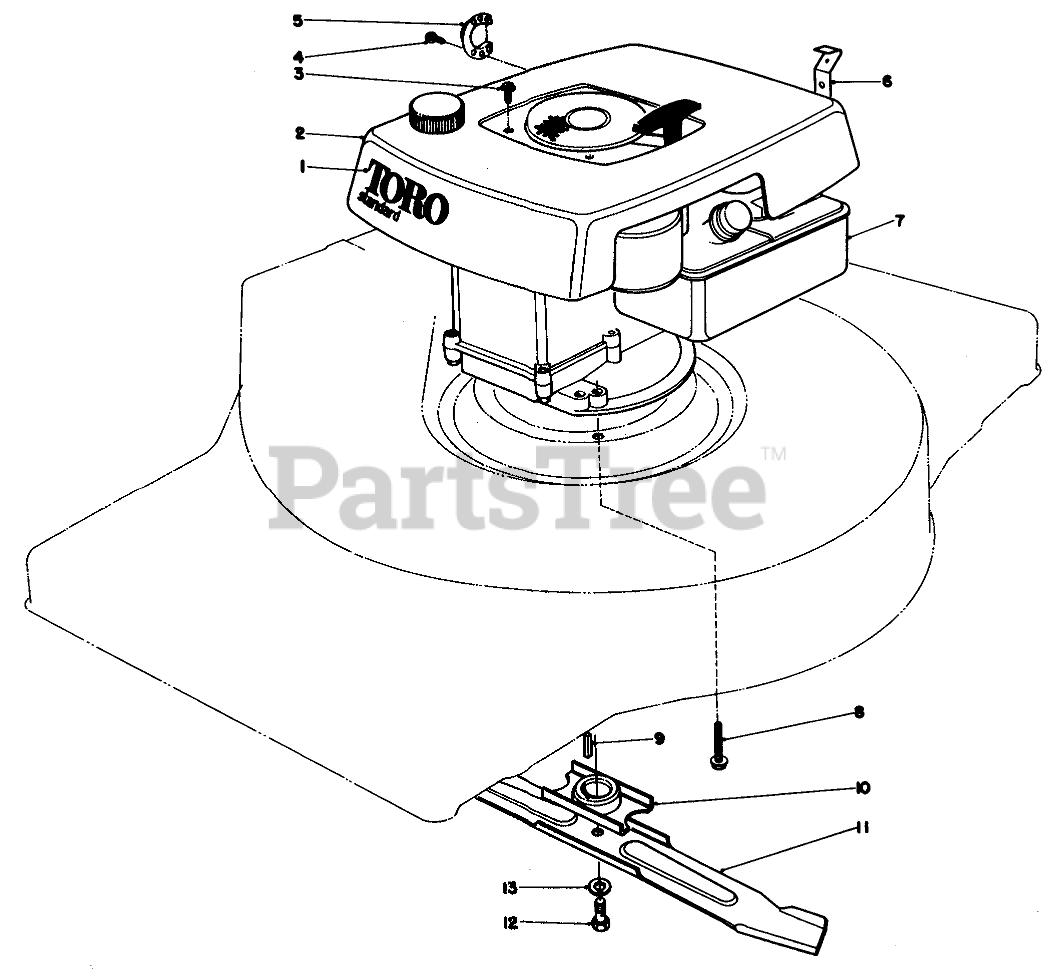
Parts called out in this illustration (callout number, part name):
1	Decal Shroud
2	SHROUD
3	8X1/2 SELF TAP SCREW
4	SCREW W/ENGINE
5	Deflector
6	Bracket Control
7	Engine
8	SCREW-HWHTF
9	KEY-SQUARE
10	Blade Retailer
11	Blade
12	SPECIAL SCREW
13	WASHER-LOCK
